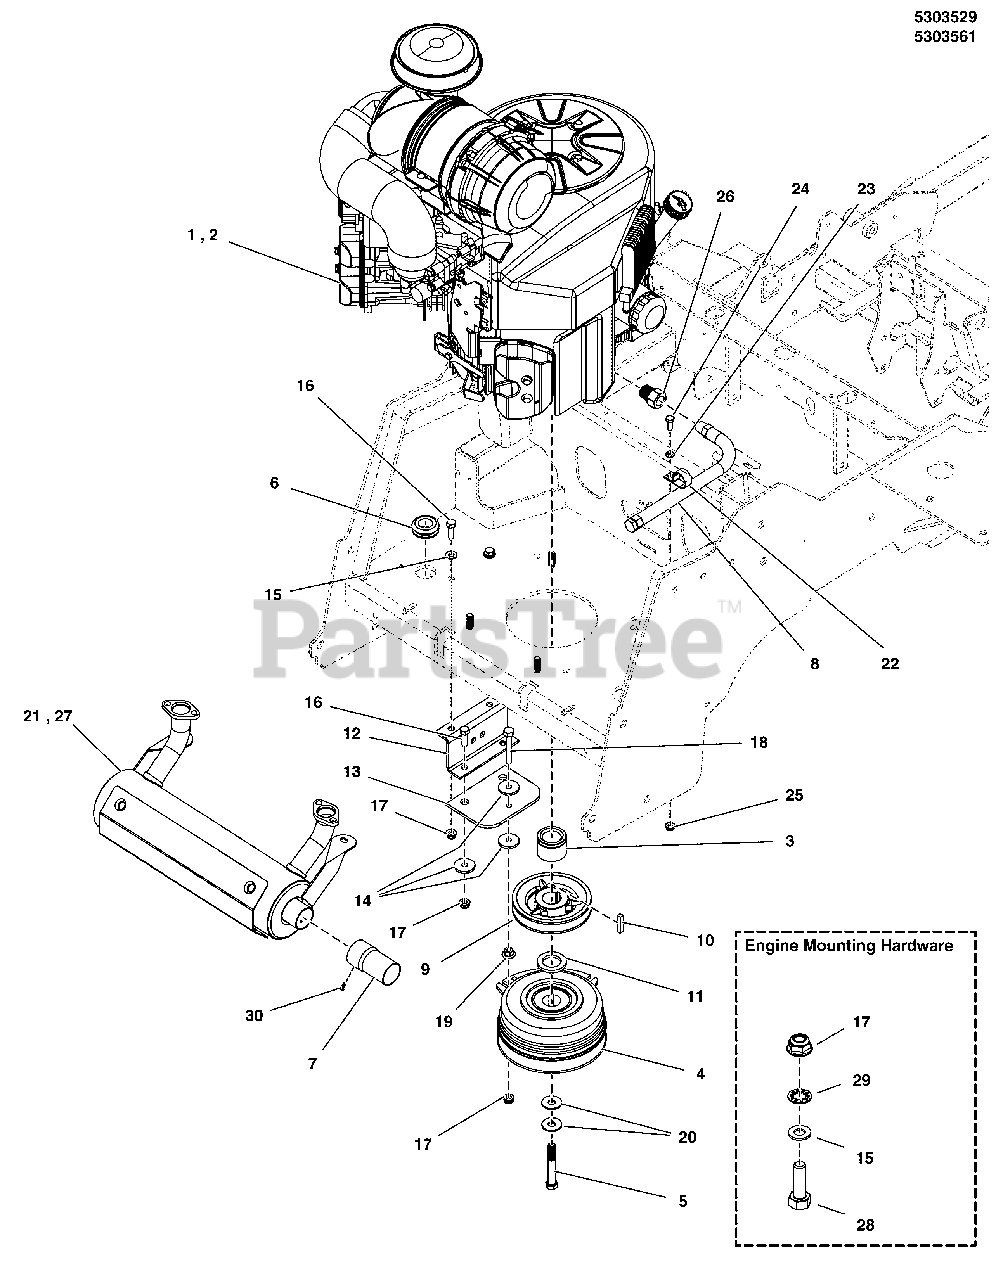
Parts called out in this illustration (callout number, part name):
1	ENGINE, B&S, VANGUARD
3	SPACER, 1.13 X 1.75 X 1.35, CZ
4	CLUTCH, WARNER, 200 FT-LB, 1.13" X 6.323
5	BOLT, CRANKSHAFT, 7/16-20 X 3, GD8
6	GROMMET, 7/8"ID, 1/4" THICK STK
7	EXTENSION, TAILPIPE, 3", BLACK
8	HOSE, OIL DRAIN
9	PULLEY, 4.75 OD X 1-1/8 BORE, BC-48
10	KEY, 1/4 SQ. X 1-1/4
11	SPACER, 1.13 X 1.75 X .25
12	ANCHOR, CLUTCH, IS600-IS700 - BLK
13	PAD, Clutch Anchor
14	WASHER, CLUTCH ANCHOR, 5/16
15	WASHER, 5/16
16	CAPSCREW, Hex Head, 5/16-18 X 1
17	NUT, Ny Lock Flange, 5/16-18
18	BOLT, 5/16-18 X 2-1/4, GD 5, TFL, ZN
19	NUT, 5/16-18 HEX SERRATED FLANGE (LARGE)
20	BELLEVILLE, WASHER, 1.1875 X .442 X .089
21	Muffler
22	CLAMP, VINYL INSULATED, 1.00
23	WASHER, 1/4, Flat, GR5 Zinc/Clear
24	CAPSCREW, Hex Head, 1/4-20 x 3/4 (stiffener to top of cover)
25	NUT, Serrated Flange, 1/4-20
26	METRIC ADAPTER, M14-1.5" TO 3/8 NPTF
27	MUFFLER, RIGHT OUTLET ASSY
28	CAPSCREW, Hex Head, 5/16-18 X 1-3/4
29	WASHER, 5/16" Internal Tooth Lock
30	SCREW,SELF-TAP,#8-32 X 3/8, WASH HEX, CZ
